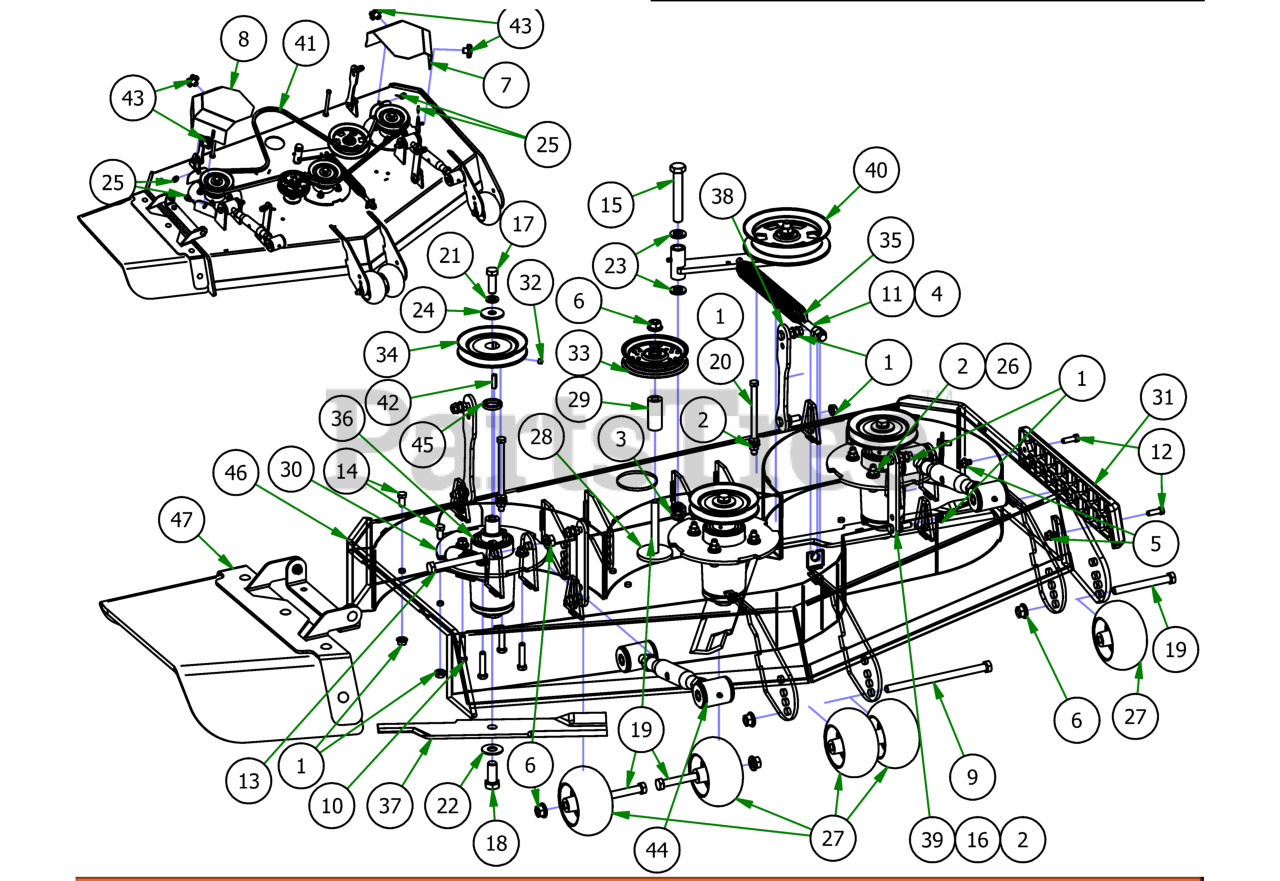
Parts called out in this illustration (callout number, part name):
1	3/8-16 HEX SERRATED FLANGE NUT HARD/ZINC
2	3/8-16 NYLON INSERT FLANGE LOCKNUT (GR.F) ZINC
3	5/8-11 NYLON INSERT JAM LOCKNUT ZINC
4	1/2-13 HEX NUT ZINC
5	5/16-18 NYLON INSERT FLANGE LOCKNUT ZINC
6	1/2-13 NYLON INSERT FLANGE LOCKNUT ZINC
7	2019 Stand On 48" Pulley Cover Trim
8	2019 Stand On 48" Pulley Cover Discharge
9	1/2-13 X 8 HEX CAP SCREW GR 5 ZINC
10	3/8-16 X 1-3/4 HEX C/S (GR.5) ZC
11	All Thread
12	5/16-18 X 1 HEX CAP SCREW (GR.5) ZINC
13	1/2-13 X 4 HEX CAP SCREW (GR.8) ZINC YELLOW
14	3/8-16 X 3/4 HEX CAP SCREW (GR.5) ZINC
15	5/8-11 X 4 HEX CAP SCREW (GR.8) ZINC YELLOW
16	3/8-16 X 1-1/2 HEX CAP SCREW (GR.5) ZINC
17	1/2-20 X 1-1/2 HEX CAP SCREW (GR.5) ZINC
18	5/8-18 X 1-1/2 HEX CAP SCREW (GR.8) ZINC YELLOW
19	1/2-13 X 4-1/2 HEX CAP SCREW (GR.5) ZINC
20	3/8-16 X 5-1/2 HEX CAP SCREW (GR.5) ZINC
21	1/2 SPLIT LOCKWASHER (GR.8) ZINC/YELLOW
22	5/8 USS FLAT WASHER (1-3/4" OD) GR.8 ZINC YELLOW
23	.635 ID X 1.120 OD X .140 THICK FLAT WASHER NYLON
24	1/2 BELLEVILLE WASHER (1-5/8 OD X .140 THK) ZINC
25	.360 ID X .983 OD X .120 THICK FLAT WASHER NYLON
26	5/16 USS FLAT WASHER (7/8 OD) ZINC
27	2019 Deck Wheel
28	MZ Deck Idler Spacer
29	2019 Revolt Stationary Idle Spacer
30	Deck Spindle Support Plate
31	REVISED TRIM BUMPER_20180226
32	5/16-24 X 1/4 SOCKET SET SCREW (CUP PT) PLAIN
33	4 3/4 Idler Pulley - ABFI-76
34	5" Spindle Deck Pulley
35	2019 Outlaw Gen2 Deck Spring
36	Spindle Assembly
37	48" ZT/Mav/Compact Outlaw Blade with Fusion
38	2019 Stand-On Rear Deck Hanger
39	2019 Revolt Front Deck Hanger
40	2019 Revolt Deck Idler Assembly
42	1/4 X 1 SQ MACHINERY KEY 1018 STL PLN
43	5/16" Knob
44	Turnbuckle
45	Spacer, 1x1.375x.25
46	2019 48 Stand On Deck Weldment
47	2019 Outlaw Gen2 Chute Assembly
